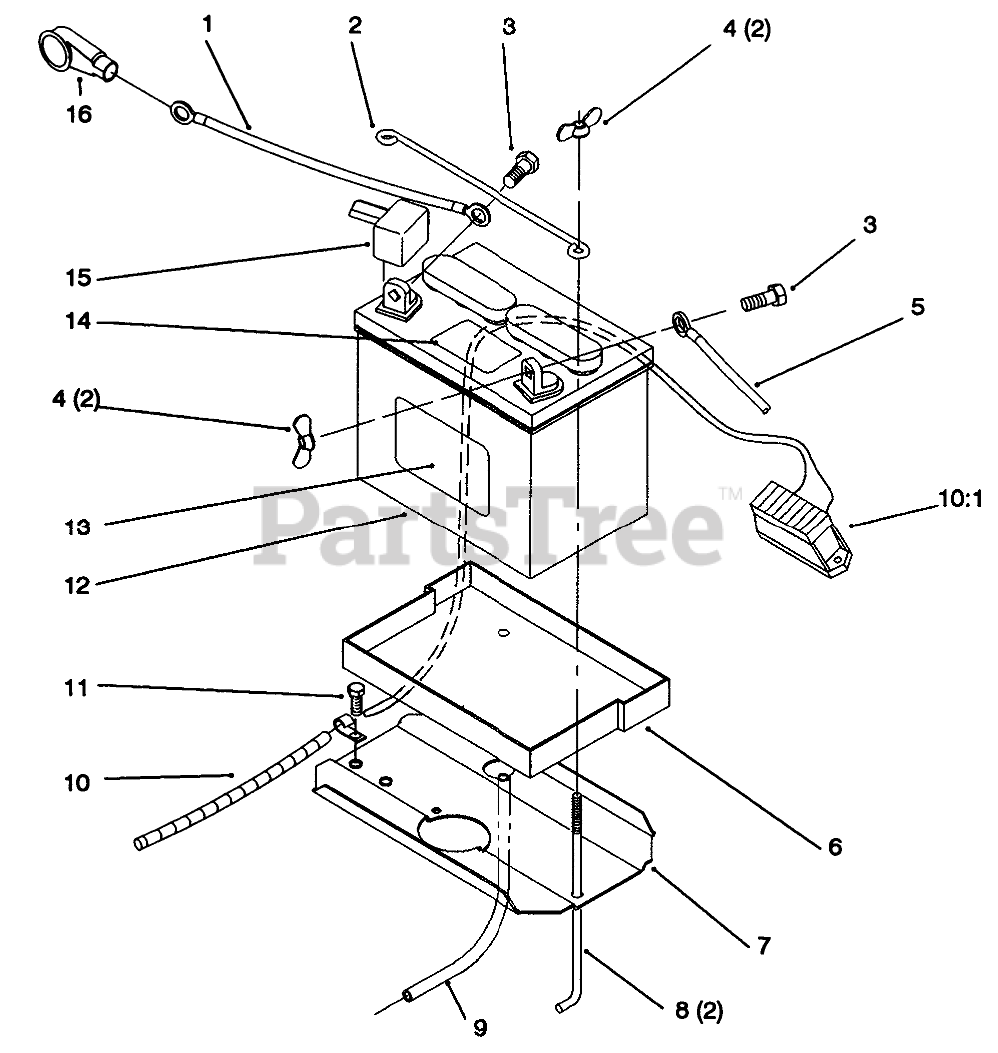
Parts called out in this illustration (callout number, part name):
1	WIRE-21 INCH
2	ROD-BATTERY HOLD DWN
3	SCREW-HH
4	NUT-WING
5	CABLE
6	TRAY-BATTERY
7	Plate-Battery
9	TUBE-21" BATTERY DRAIN
10	HARNESS - WIRE
10:1	FUSE-HOLDER 4 WAY
11	SCREW-HWHTF
12	Battery
15	Boot
16	BOOT-INSULATOR, TERMINAL
